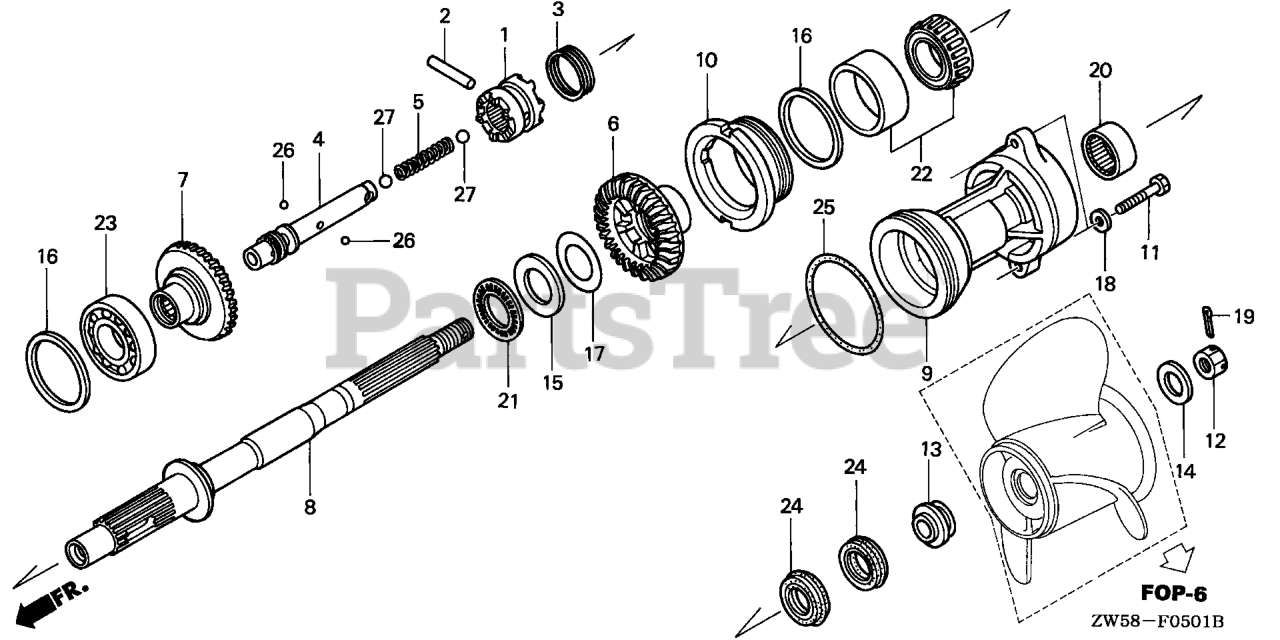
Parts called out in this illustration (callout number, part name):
1	SHIFTER, CLUTCH
2	PIN, SHIFTER (8X47)
3	RING, CROSS PIN
4	SLIDER, SHIFT
5	SPRING, SHIFT
6	GEAR, BEVEL (F)(COUNTER ROTATION)
7	GEAR, BEVEL (R)(COUNTER ROTATION)
8	SHAFT, PROPELLER (COUNTER ROTATION)
9	HOLDER, PROPELLER SHAFT *NH282MU* (COUNTER ROTATION) (OYSTER SILVER METALLIC-U)
10	HOLDER, BEARING
11	BOLT, HEX. (10X40)
12	NUT, CASTLE (18MM)
13	WASHER, PROPELLER THRUST
14	WASHER, PLAIN (18.5MM)
15	WASHER, THRUST BEARING
16	SHIM A, BEVEL (0.10) (FR.)
16	SHIM B, BEVEL (0.15) (FR.)
16	SHIM C, BEVEL (0.30) (FR.)
16	SHIM D, BEVEL (0.50) (FR.)
17	SHIM A, THRUST (0.10)
17	SHIM B, THRUST (0.15)
17	SHIM C, THRUST (0.30)
17	SHIM D, THRUST (0.50)
18	WASHER, PLAIN (10MM)
19	PIN, SPLIT (4.0)
20	BEARING, NEEDLE (30X37X26)
21	BEARING, THRUST (F)
22	BEARING, TAPERED (50X82X21.5)
23	BEARING, RADIAL BALL (40X82X18)
24	SEAL, WATER (30X45X7)
25	O-RING (94X4.1)
26	BALL, STEEL (#6) (3/16)
27	BALL, STEEL (#11) (11/32)
